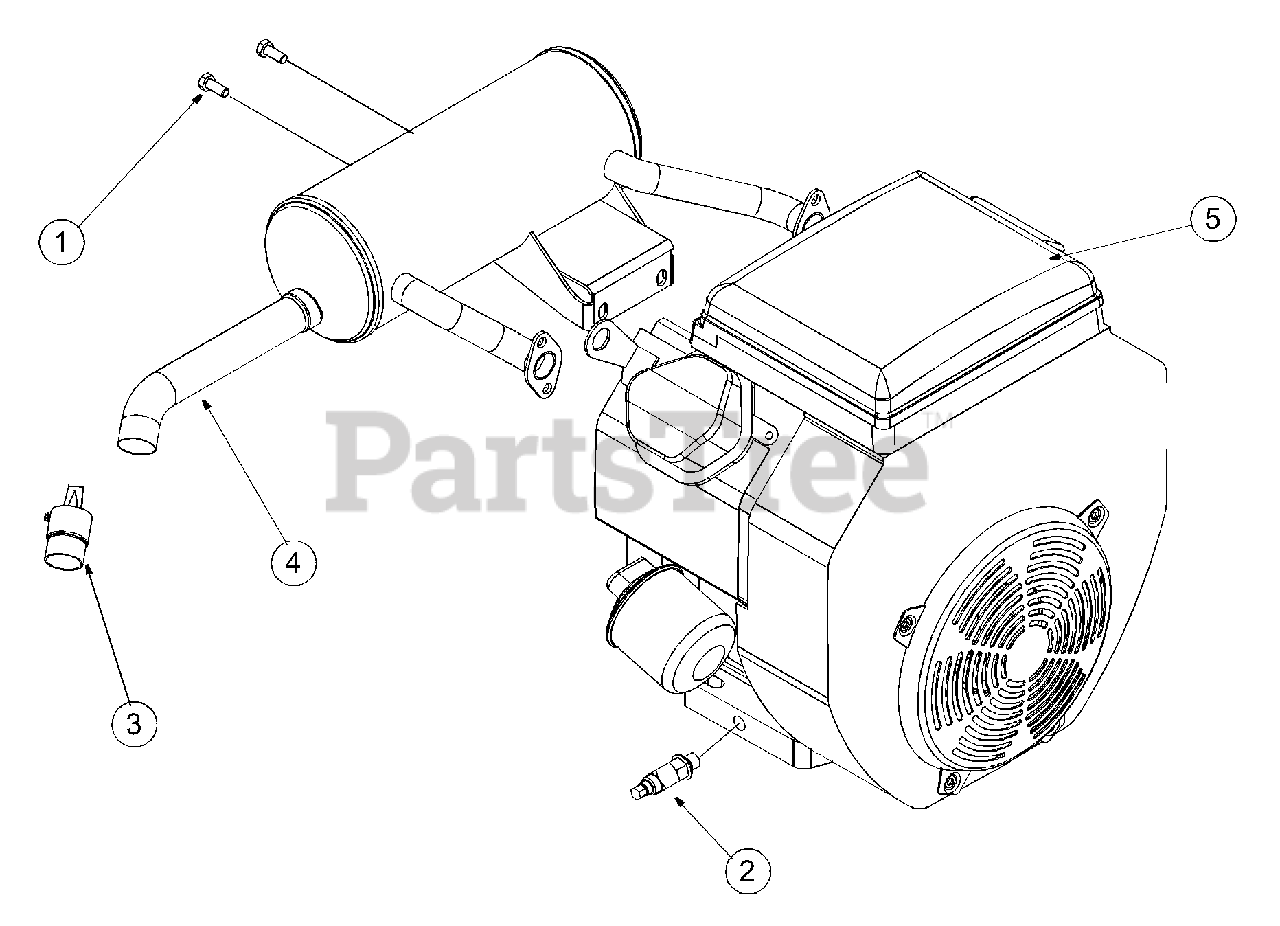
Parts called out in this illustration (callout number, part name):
1	Screw, M8
2	Valve, Oil Drain
3	Spark Arrestor
4	Muffler, Honda GX620
5	Engine, Honda GX618K1
